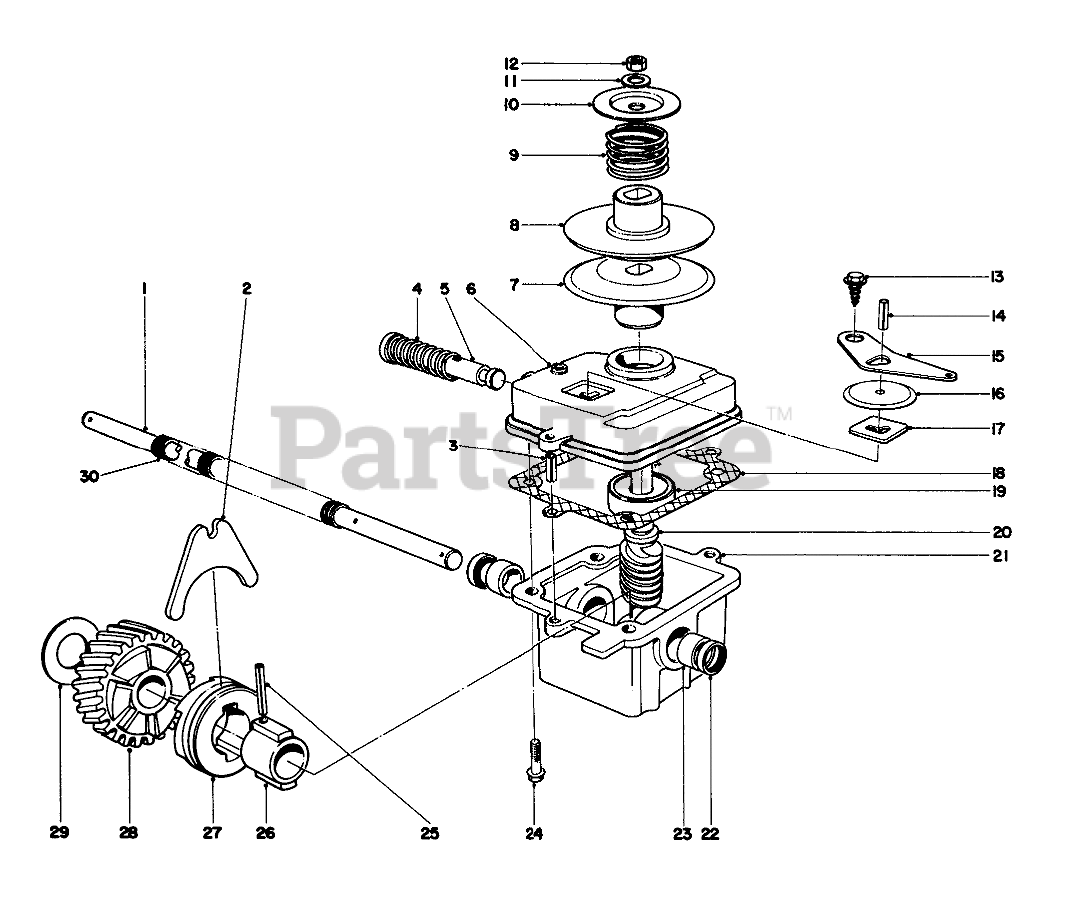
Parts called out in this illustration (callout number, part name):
1	Drive Shaft
2	SHIFTER FORK
3	3/16 X 1/2 ROLL PIN
4	SPRING
5	Shift Rod
6	GEAR CASE COVER
7	LOWER PULLEY HALF
8	UPPER PULLEY HALF
9	COMPRESSION SPRING
10	SPRING RETAINER
11	WASHER-FLAT
12	NUT-HEX, SIDE DEFORM
13	Screw
14	PIN-ROLL
15	SHIFTER ARM
16	TRANS DUST COVER
17	LATCH PLATE
18	GASKET
19	Bearing
20	Shaft-Worm
21	Gear Case (Incl. Ref. #22 & 23)
22	Seal
23	Bushing
24	Screw
25	COIL PIN
26	SLEEVE
27	CLUTCH JAW
29	THRUST WASHER
30	DRIVE SHAFT COVER
